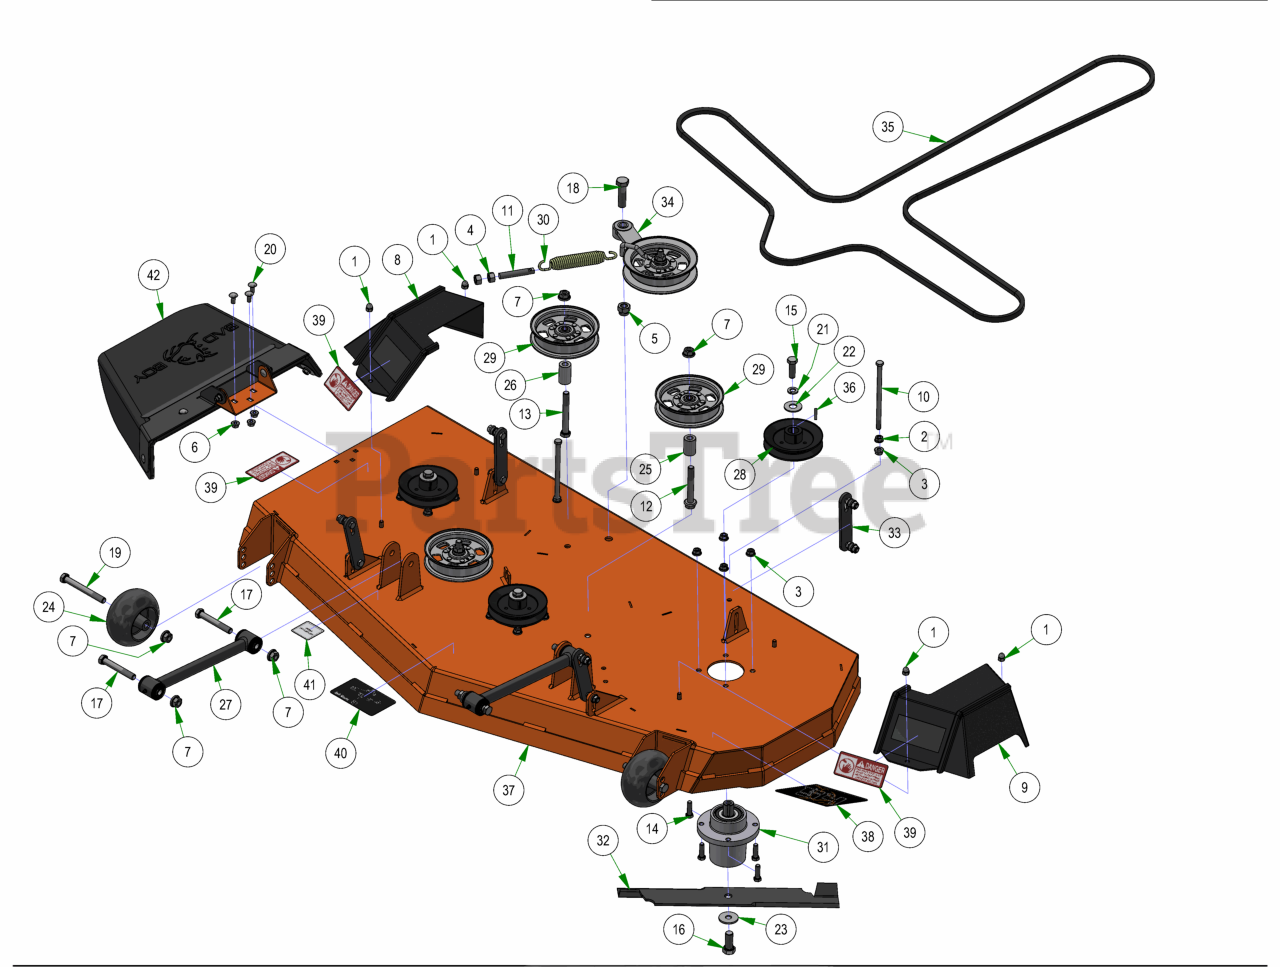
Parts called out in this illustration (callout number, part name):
1	5/16-18 ACORN NUT HIGH-CROWN ZC
2	3/8-16 HEX SERRATED FLANGE NUT HARD/ZINC
3	3/8-16 NYLON INSERT FLANGE LOCKNUT (GR.F) ZINC
4	1/2-13 HEX NUT ZINC
5	5/8-11 NYLON INSERT LOCKNUT ZINC
6	5/16-18 NYLON INSERT FLANGE LOCKNUT ZINC
7	1/2-13 NYLON INSERT FLANGE LOCKNUT ZINC
8	2021 Maverick 54”/60” RH Pulley Cover
9	2021 Maverick 54”/60” LH Pulley Cover
10	3/8-16 X 6.5 HEX CAP SCREW (GR.5) ZINC
11	All Thread
12	1/2-13 X 3-1/2 HEX FLANGE BOLT (GR.8) ZINC
13	1/2-13 X 4 HEX CAP SCREW (GR.8) ZINC YELLOW
14	3/8-16 X 1-1/4 HEX CAP SCREW (GR.5) ZINC
15	1/2-20 X 1-1/2 HEX CAP SCREW (GR.5) ZINC
16	5/8-18 X 1-1/2 HEX CAP SCREW (GR.8) ZINC YELLOW
17	1/2-13 X 3-1/2 HEX CAP SCREW (GR.5) ZINC
18	5/8-11 X 2-1/4 HEX CAP SCREW (GR.5) ZINC
19	1/2-13 X 4-1/2 HEX CAP SCREW (GR.5) ZINC
20	5/16-18 x 3/4 Carriage Bolt
21	1/2 SPLIT LOCKWASHER (GR.8) ZINC/YELLOW
22	5/8 USS FLAT WASHER (1-3/4" OD) GR.8 ZINC YELLOW
23	1/2 BELLEVILLE WASHER (1-5/8 OD X .140 THK) ZINC
24	2019 Deck Wheel
25	.502 ID X .750 OD X 1.500 Long Spacer
26	1 3/4" Pulley Spacer
27	Hybrid Turnbuckle/Deck Locator
28	54 MZ Spindle Pulley
29	5-3/4 Idler Pulley
30	Deck Idler Spring
31	Spindle Assembly-MZ
32	54" MZ Fusion Blade
33	Deck Hanger Assembly
34	Maverick HD & Down Deck Idler Assembly
35	B155.75 Deck Belt
36	3/16 X 1 SQ MACHINERY KEY 1018 STL ZINC
37	2025 54" x 4" Deck
38	54" Grip Deck Decal
39	Danger Decal-Spindle/Discharge
40	Deck Belt Route Decal
41	Deck Impact Patent Decal 9591803
42	MZ Discharge Chute Assembly
